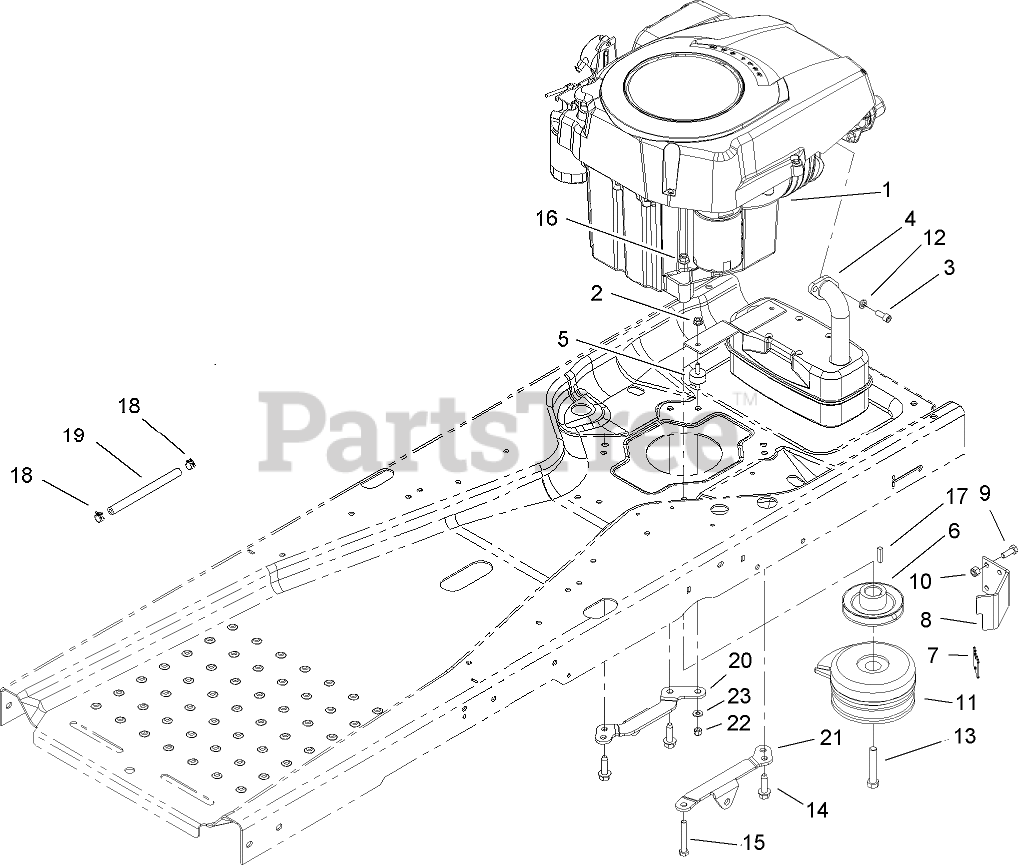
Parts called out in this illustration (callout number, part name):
2	NUT-HF
3	SCREW-HSH
4	MUFFLER-KOHLER
5	ISOLATOR
6	PULLEY-ENGINE
7	BUMPER
8	STOP-CLUTCH
9	SCREW-HH
10	NUT-LOCK, NI
11	CLUTCH-ELECTRIC, PTO
12	WASHER-LOCK
13	SCREW-HH
14	SCREW-TAPTITE
15	SCREW-HH
16	NUT-LOCK, NI
18	CLAMP-HOSE
19	HOSE-FUEL
20	SUPPORT-HYDRO, RH
21	SUPPORT-HYDRO, LH
22	NUT-LOCK, NI
23	WASHER-FLAT
